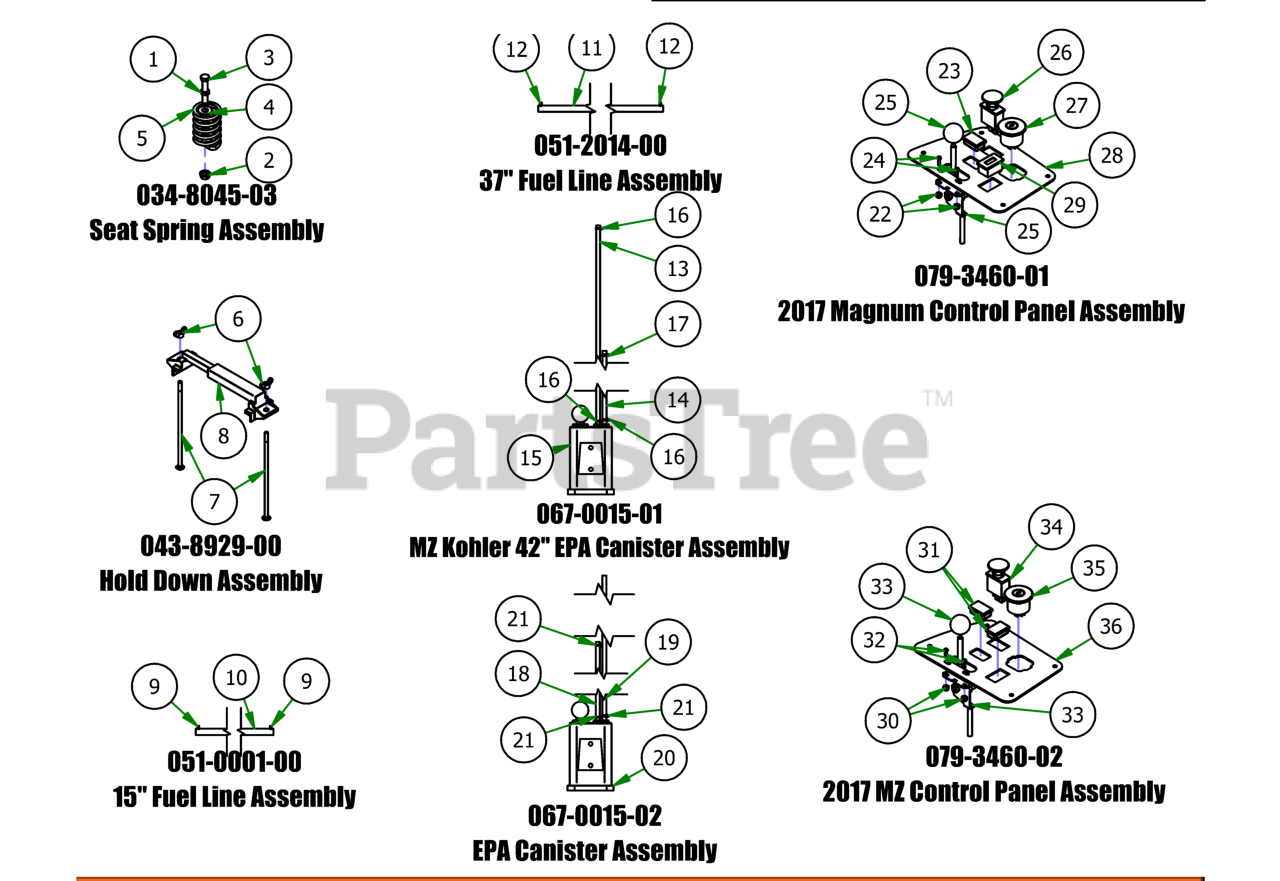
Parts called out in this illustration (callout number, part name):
1	3/8-16 Half Jam Nut
2	3/8" Flange Nut
3	3/8"-16 x 2" Gr 5 Hex Bolt
4	3/8" Flat Washer
5	Seat Spring
6	1/4" Wing Nut
7	1/4-20 X 8 Carriage Bolt
8	Battery Hold Down
9	1/4 Fuel Hose Clamp
10	1/4 Fuel Line
11	37" 1/4 Fuel Line
12	1/4 Fuel Hose Clamp
13	3/16 Vinyl Tubing, 53"
14	3/16" Clear Vinyl Tubing, 44"
15	Carbon Canister for Magnum/MZ
16	8.6mm Hose Clamp
17	3/16" Vinyl Hose Clamp
18	3/16 Vinyl Tubing, 44"
19	3/16" Clear Vinyl Tubing, 52"
20	Carbon Canister for Magnum/MZ
21	8.6mm Hose Clamp
22	10-24 Nylon Insert Locknut Zinc Orange Nylon
23	Light Plug
24	10-24 X 5/8 BS Button Head Bolt
25	Throttle Lever Assembly
26	PTO Engager
27	Ignition Switch
28	Control Panel
29	Tachometer
30	10-24 Nylon Insert Locknut Zinc Orange Nylon
31	Light Plug
32	10-24 X 5/8 BS Button Head Bolt
33	Throttle Lever Assembly
34	PTO Engager
35	Ignition Switch
36	Control Panel
